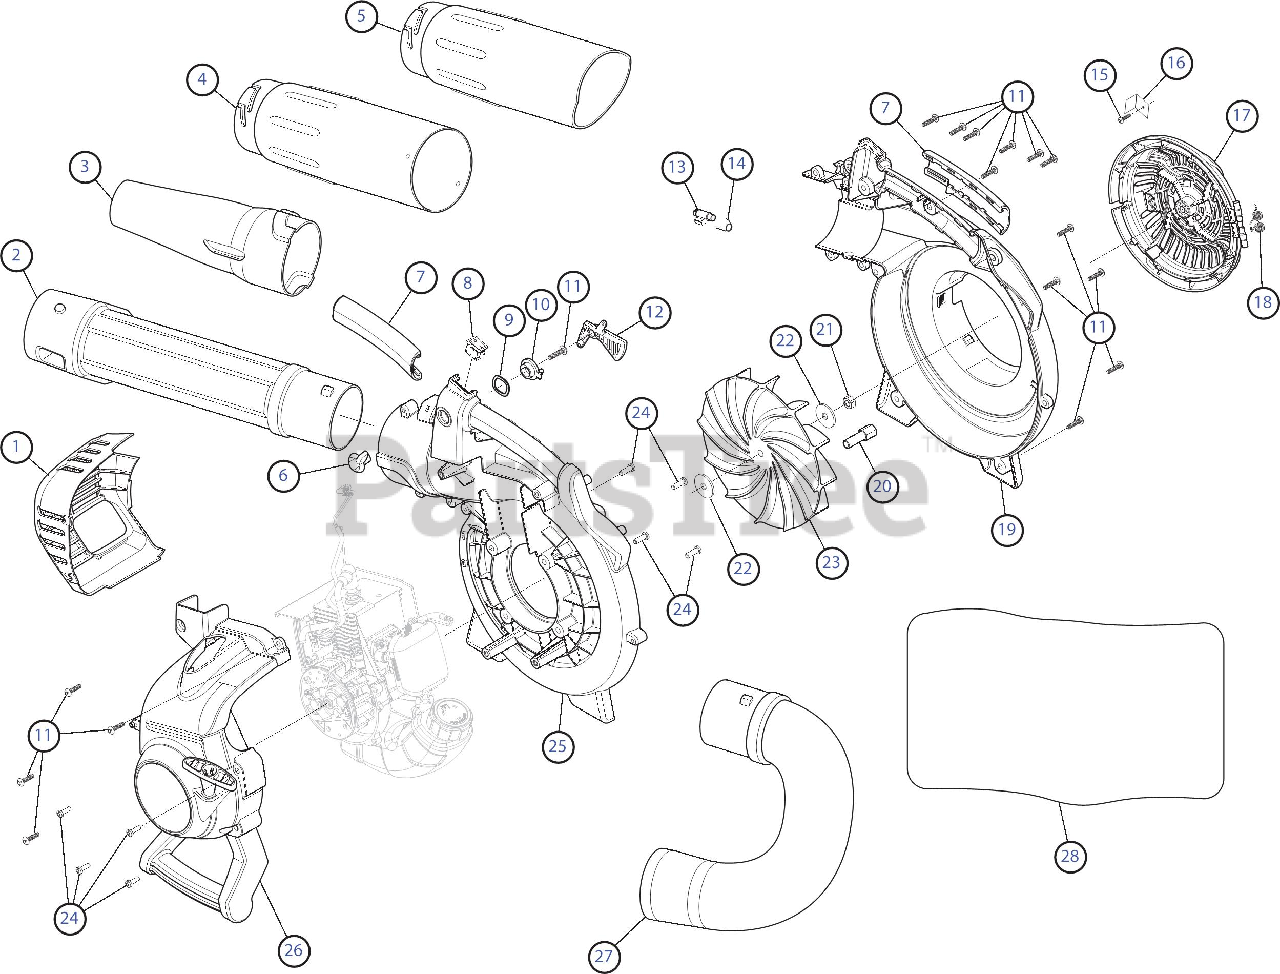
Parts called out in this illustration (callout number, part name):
1	Muffler Cover Assembly (Incl. 11)
2	Upper Tube
3	Nozzle
4	Upper Vac Tube
5	Lower Vac Tube
6	Outer Trigger Lock
7	Handle Grips
9	Wavey Washer
10	Inner Trigger Lock
12	Throttle Trigger
13	Latch Tube
14	Latch Spring
15	Screw
16	Door Lock
17	Intake Cover
18	Spring
19	Impeller Housing
20	Adapter
21	Nut
22	Washer
23	Impeller
24	Screw
25	Impeller Housing
26	Engine Cover Assembly (Incl. 11 & 24)
